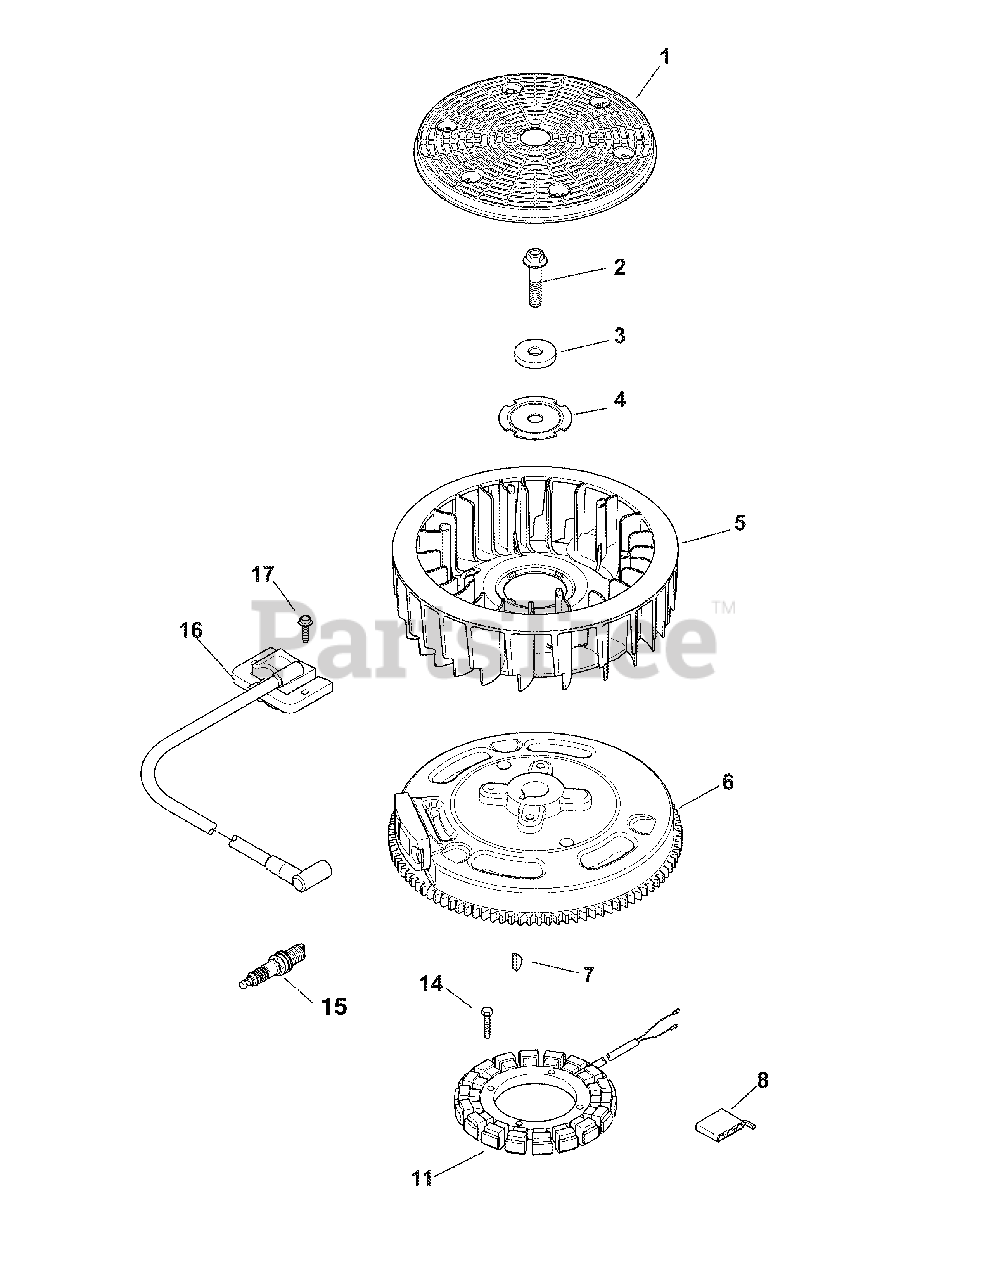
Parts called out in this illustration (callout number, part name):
2	Flg. Screw, M10 x 1.5 x 45
3	Flat Washer, 13.32
4	Fan Mounting Plate
5	Fan
6	Flywheel Assembly
7	Key, 3.16 x 5.8
11	15 Amp Stator Kit
14	Thd. Frm. Screw, M5 x 0.8 x 25
15	Spark Plug
16	Ignition Module Kit
17	Flg. Thd. Frm. Screw, M5 x .8 x 20
